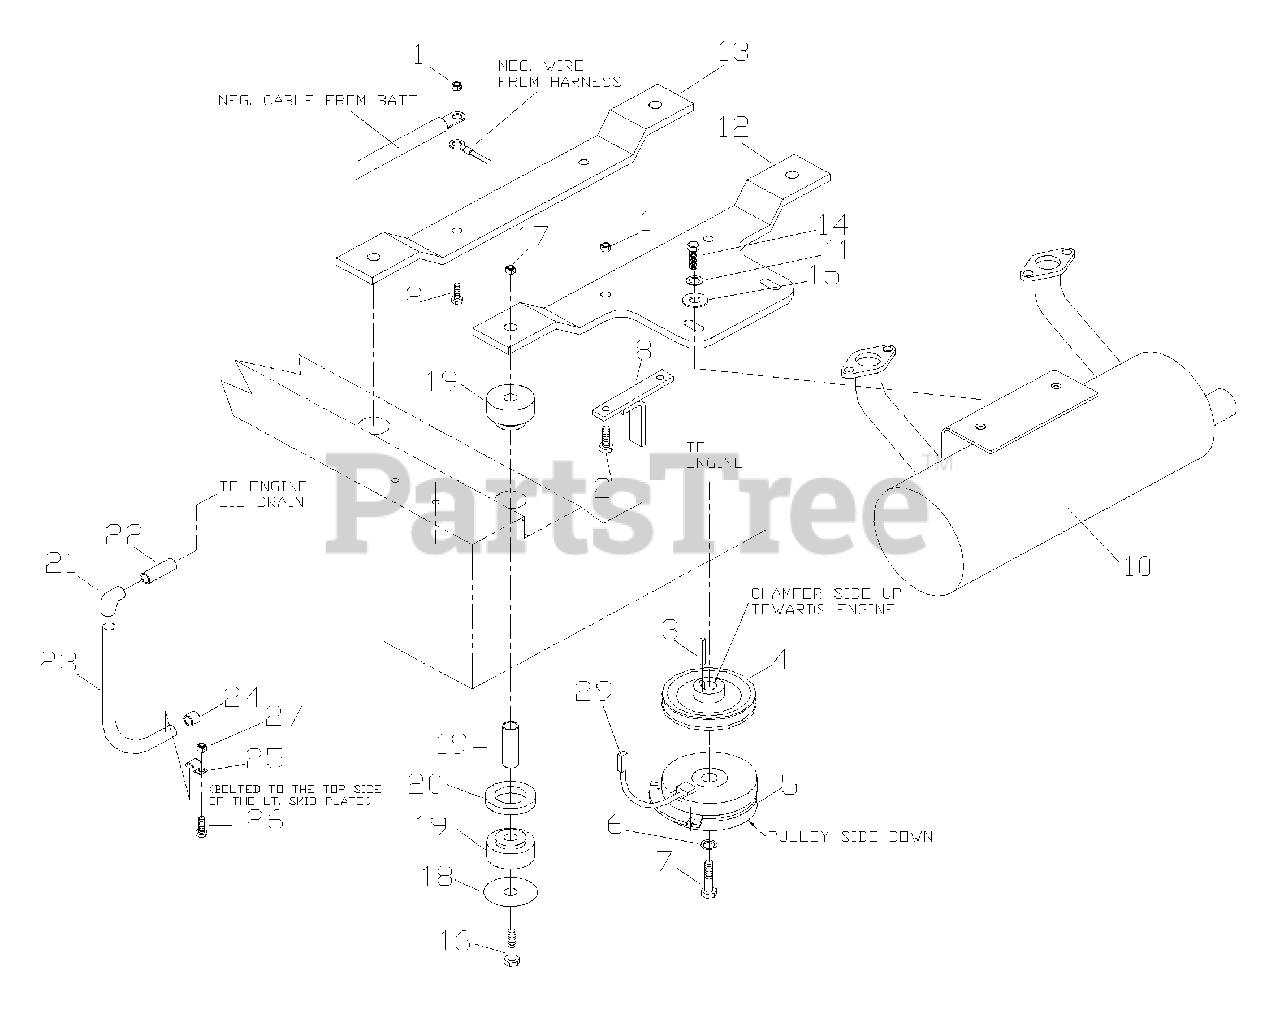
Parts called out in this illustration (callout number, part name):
1	NUT 5/16 LOCK
2	HCS 5/16 X 1.75
3	KEY 1/4 SQ.
6	WASHER 7/16 LOCK
7	HCS 7/16F X 2.5
8	CLUTCH TIE DOWN
9	KOHLER PIGTAIL
11	WASHER 5/16 LOCK
12	ENGINE MOUNT
13	ENGINE MOUNT
14	HCS 5/16 X .750
15	WASHER 5/16 FLAT
16	HCS 1/2 X 3.25
17	NUT 1/2 NYLOC
22	3/8 NPT PIPE
23	OIL DRAIN HOSE
26	HCS 1/4 X .750
27	NUT 1/4 CTR. LOCK
29	CLUTCH PIGTAIL
